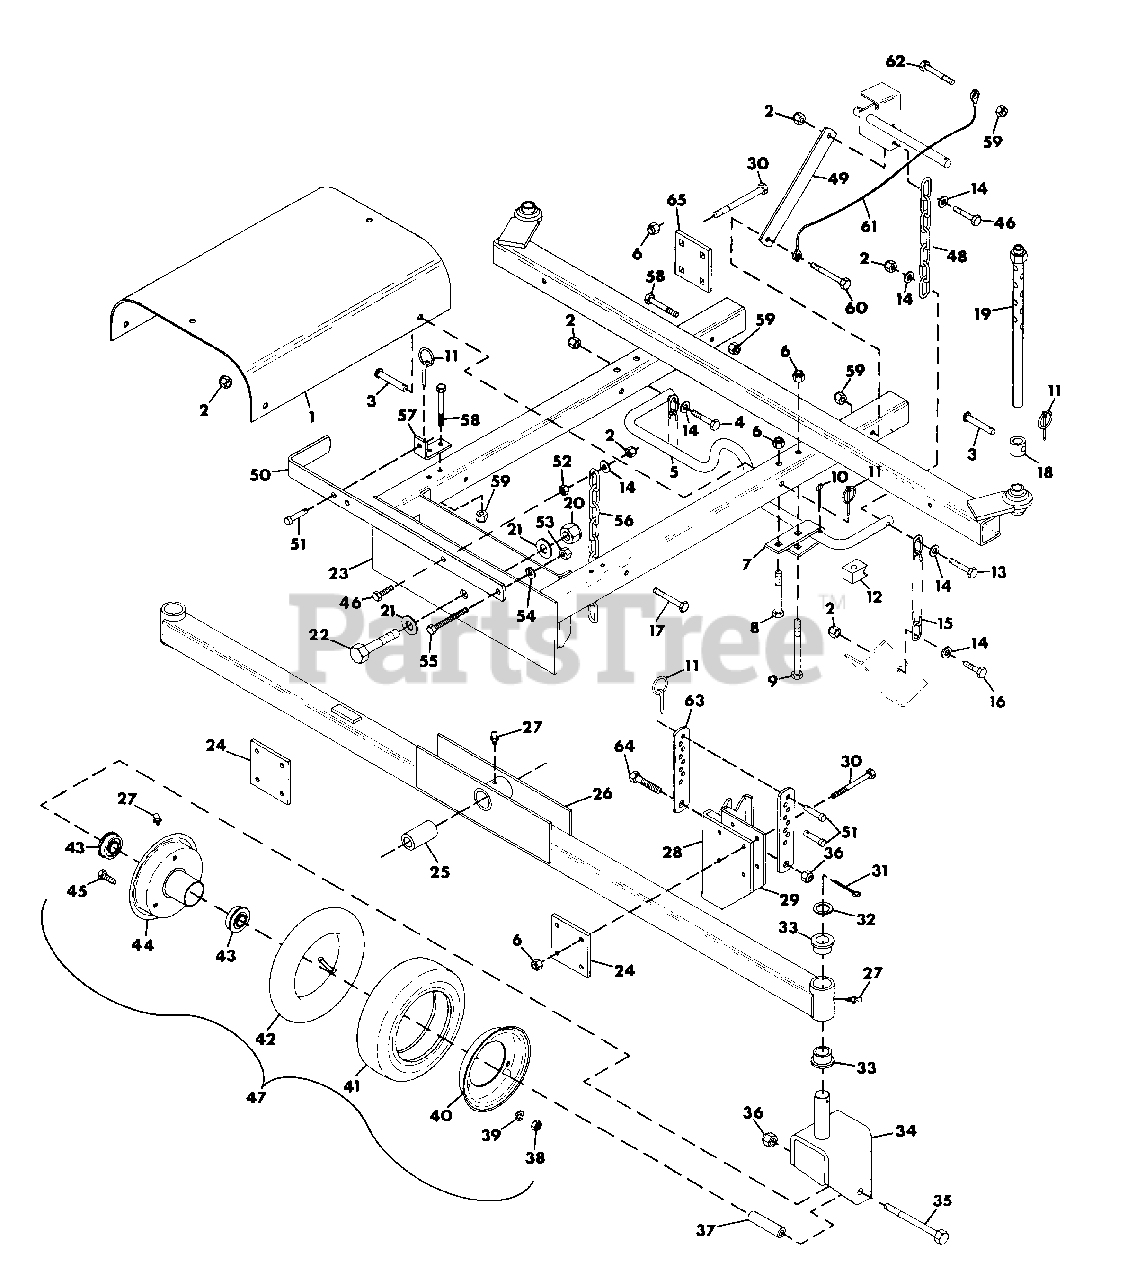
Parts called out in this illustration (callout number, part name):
1	GUARD, PTO SHAFT
2	NUT, LOCK 5/16-18
3	PIN, CLEVIS 3/8X2.62
4	BOLT, HEX 5/16-18X1.50
5	ARM, PIVOT
6	NUT, LOCK 3/8-16
7	BRACKET, AXLE SUPPORT
8	BOLT, HEX 3/8-16X3.00
9	BOLT, HEX 3/8-16X4.00
10	PIN, COTTER 1/8X1.25
11	KLIK PIN
12	STOP, NYLON
13	BOLT, HEX 5/16-18X1.75
14	WASHER, FLAT .406X.812X.065
15	CHAIN, LIFT
16	BOLT, HEX 5/16-18X1.00
17	BOLT, HEX 5/16-18X2.50
18	SPACER, HEIGHT ADJUSTMENT
19	WELDMENT, HEIGHT ADJUSTMENT
20	NUT, LOCK 3/4-10
21	WASHER, FLAT .812X.469X.130
22	BOLT, HEX 3/4-10X4.50
23	WELDMENT, MOWER FRAME
24	PLATE, ADJUSTMENT CLAMP
25	TUBE, PIVOT
26	WELDMENT, AXLE
27	FITTING, LUBE 1/4-28
28	PLATE, HEIGHT ADJUSTMENT-L.H.
28	PLATE, HEIGHT ADJUSTMENT-R.H.
29	PLATE, HEIGHT ADJUSTMENT-L.H.
29	PLATE, HEIGHT ADJUSTMENT-R.H.
30	BOLT, HEX 3/8-16X3.25
31	PIN, COTTER 3/16X1.62
32	RACE, BEARING THRUST
33	BUSHING, PIVOT
34	WELDMENT, CASTER FORK
35	BOLT, HEX 1/2-13X5.00
36	NUT, LOCK 1/2-13
37	BUSHING, WHEEL .520X.750X3.312
38	NUT, HEX 3/8-24
39	WASHER, LOCK 3/8 SP HEAVY
40	WHEEL, HALF PLAIN
41	TIRE, GAUGE WHEEL
42	TUBE, INNER
43	BEARING, GAUGE WHEEL
44	WHEEL, HALF WITH TUBE
45	BOLT, HEX 3/8-24X.75
46	BOLT, HEX 5/16-18X1.25
47	WHEEL, GAUGE
48	CHAIN, LIFT
49	BAR, DECK LIFT
50	BAR, LIFT
51	PIN, CLEVIS
52	NUT, JAM 5/16-18
53	NUT, JAM 3/8-16
54	WASHER, LOCK 3/8
55	BOLT, 3/8-16X3 SPECIAL
56	CHAIN, HEIGHT ADJ.
57	BRACKET, LIFT PIVOT
58	BOLT, 5/16-24X2.75
59	NUT, LOCK 5/16-24
60	BOLT, 5/16-24X3.5
61	CABLE, STOP
62	BOLT, 5/16-24X2.25
63	STRAP, ADJUSTMENT
64	BOLT, HEX 1/2-13X2.00
65	PLATE, ATTACHMENT CLAMP
NS	DECAL, PRO MASTER-60
